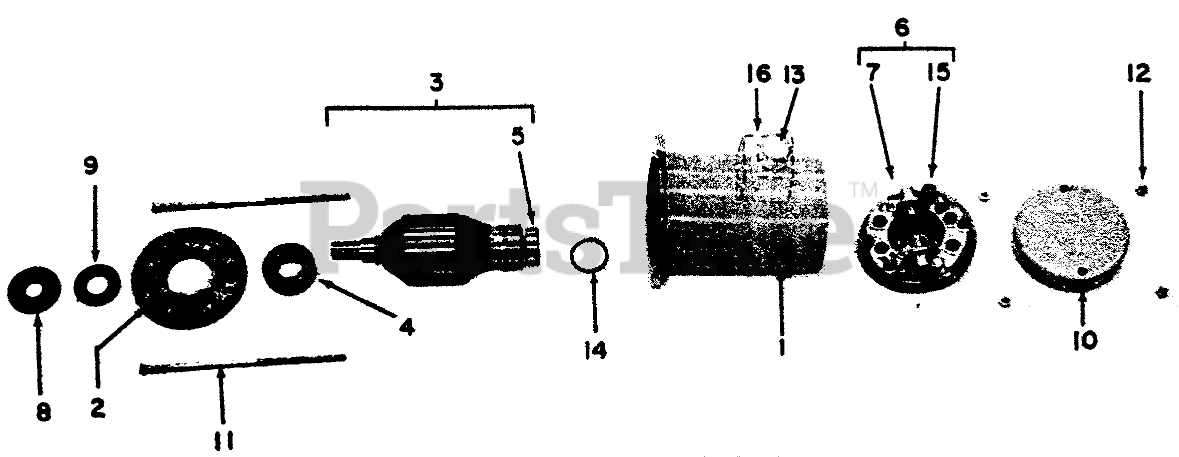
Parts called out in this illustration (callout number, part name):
1	Shell and Magnet Aim.
2	Shaft End Bell with Bearing, Ref. 4
3	Armature & Bearing Asm., Ref. 4 & 5
4	Shaft End Bearing
5	Commutator End Bearing
6	Com. End Bell Asm. (With Brushes) Ref. 7 & 15
7	Brush Asm.
8	External Bearing Shield
9	Internal Bearing Shield
10	Terminal Cover
11	Tie Bolt
12	Twin Whiz Lock Nut (1/4-20)
13	Circuit Breaker
15	Brush Holder Spring
